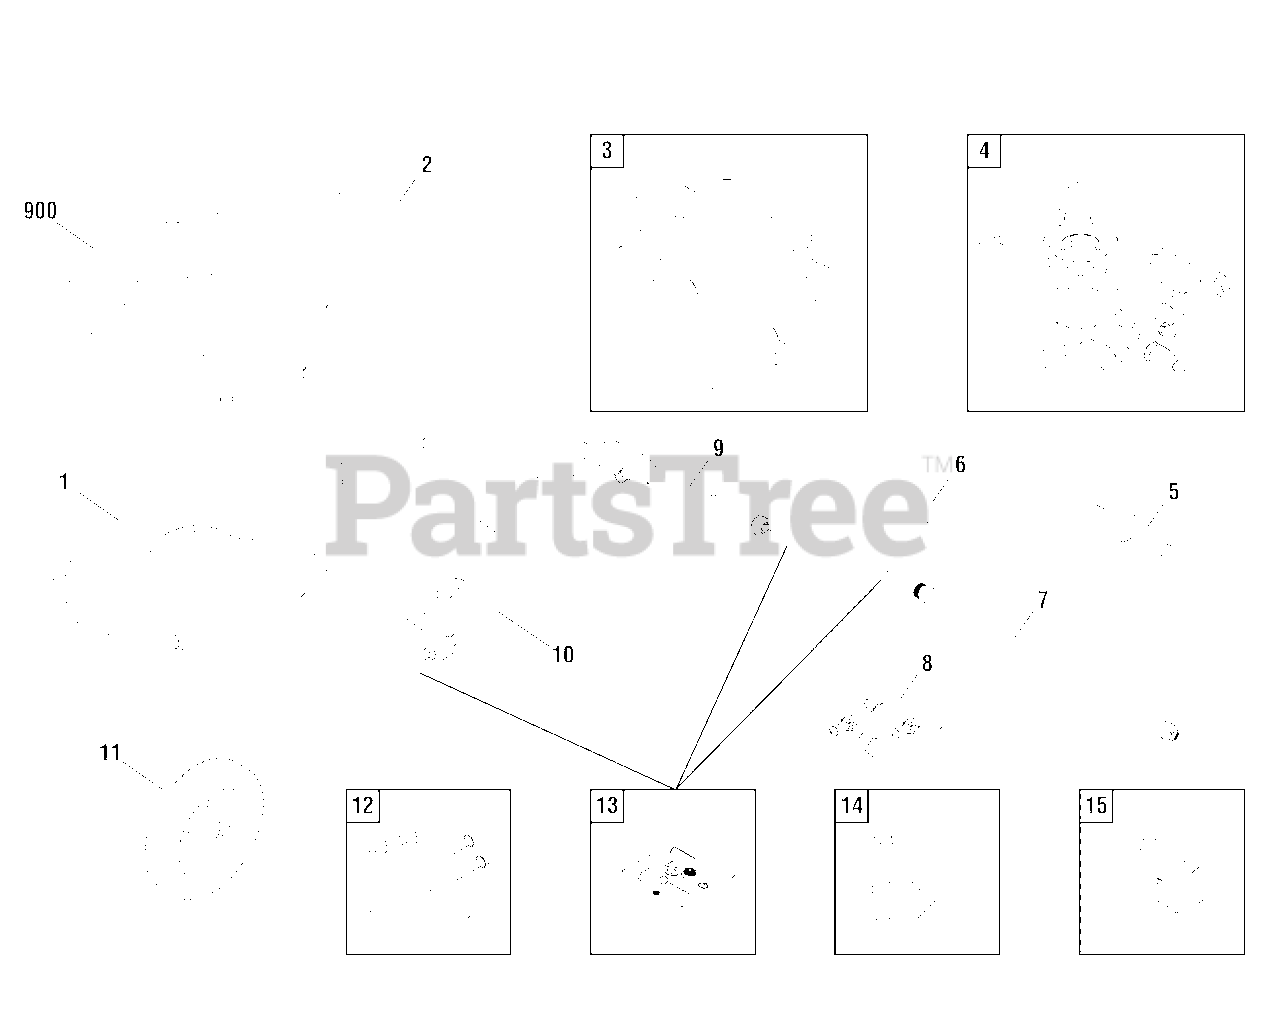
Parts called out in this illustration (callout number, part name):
9	GUN
10	HOSE
12	MOUNT-VIBRATION
14	KIT-HARDWARE PUMP MOUNTING
900	** ENGINE
